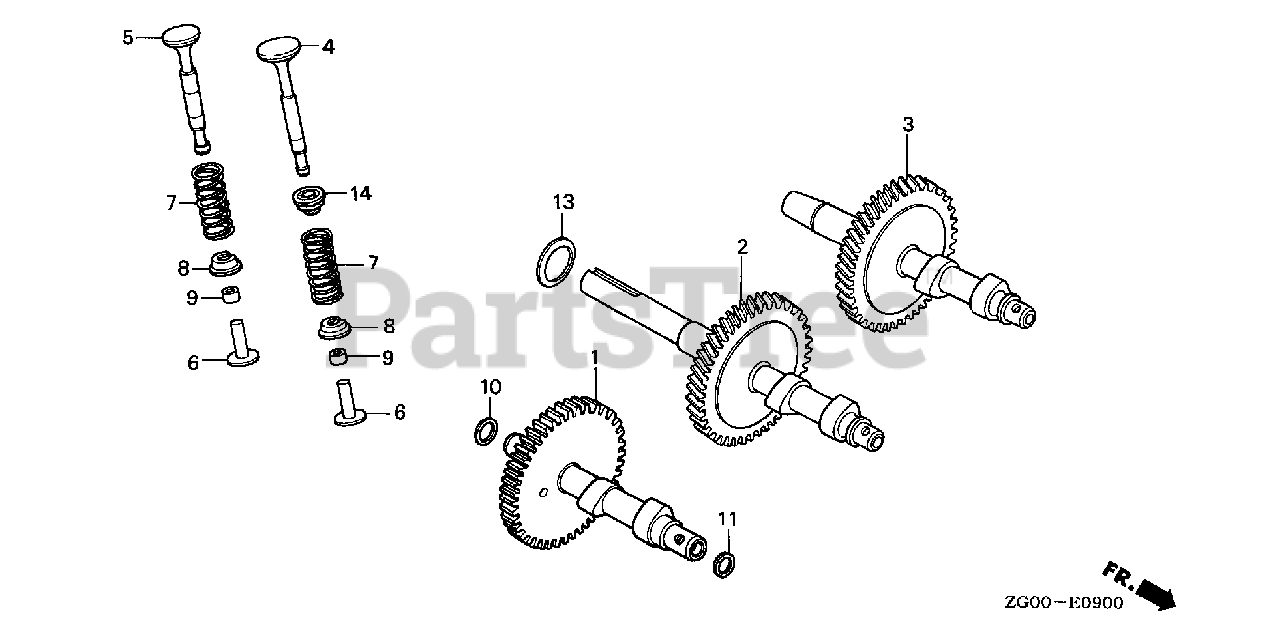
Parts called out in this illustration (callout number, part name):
4	VALVE, IN.
5	VALVE, EX.
6	LIFTER, VALVE
7	SPRING, VALVE
8	RETAINER, VALVE SPRING
8	RETAINER, VALVE SPRING (NOT AVAILABLE)
9	ADJUSTER, TAPPET CLEARANCE (3.15)
9	ADJUSTER, TAPPET CLEARANCE (3.25)
9	ADJUSTER, TAPPET CLEARANCE (3.34)
9	ADJUSTER, TAPPET CLEARANCE (3.43)
9	ADJUSTER, TAPPET CLEARANCE (3.52)
9	ADJUSTER, TAPPET CLEARANCE (3.61)
9	ADJUSTER, TAPPET CLEARANCE (3.72)
9	ADJUSTER, TAPPET CLEARANCE (3.82)
10	WASHER (10MM)
10	WASHER, THRUST (9.9MM)
11	WASHER (10MM)
11	WASHER, THRUST (9.9MM)
